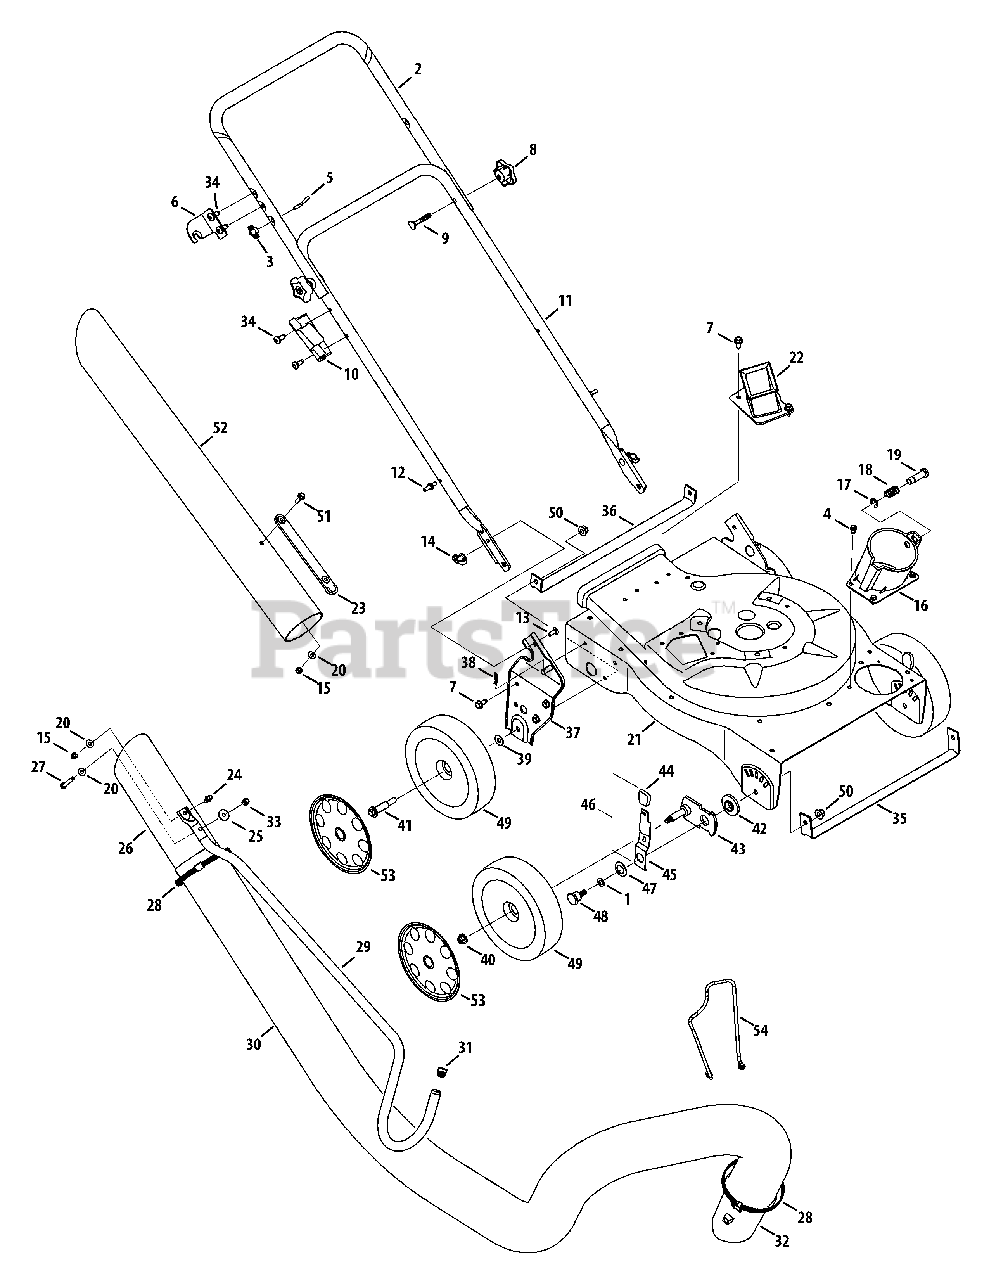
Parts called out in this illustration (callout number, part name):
1	Thrust Washer.375 ID x.70 OD
4	Screw, 1/4-20 x .500
6	Upper Handle Bracket
7	Hex Cap Screw 5/16-12 x.750
9	Carriage Bolt
10	Nozzle Handle Clip
13	Carriage Screw 1/4-20 x.75
14	Wing Nut 1/4-20
15	Hex Lock Nut, 1/4-20
16	Hose Base Adapter Assembly
17	E Ring.500 Dia
18	Compression Spring
19	Clevis Pin
20	Flat Washer.271 ID x.630 OD
21	Upper Flail Housing
22	Chipper Chute Assembly
23	Chute Strap
26	Hose Nozzle
27	Hex Cap Screw 1/4-20 x 2.625
28	Adjustment Clamp
30	Vacuum Hose
31	Handle Plug
32	Hose Adapter, 173CC
33	Cap Lock Nut, 1/4-20
34	TT Screw, 5/16-18 x .750
35	Front Wheel Support Brace
36	Rear Wheel Support Brace
37	Handle Bracket Ass’y RH
37	Handle Brkt Ass’y LH
38	Cotter Pin
39	Bell Washer.401 ID x.870 OD
40	Flange Lock Nut, 3/8-16
41	Shoulder Screw 3/8-16
42	Height Adjustment Bearing
43	Pivot Arm Assembly
44	Height Adjustment Knob
45	Spring Lever
46	Height Lever Assembly
47	Bell Washer.760 ID x.25 OD
48	Shoulder Screw,.750 x.500
49	Wheel, 8 x 2
50	Flange Lock Nut, 3/8-16
51	Screw, 1/4-20 x .75
52	Hose Extension
53	Hubcap, 8"
54	Tube Holder
